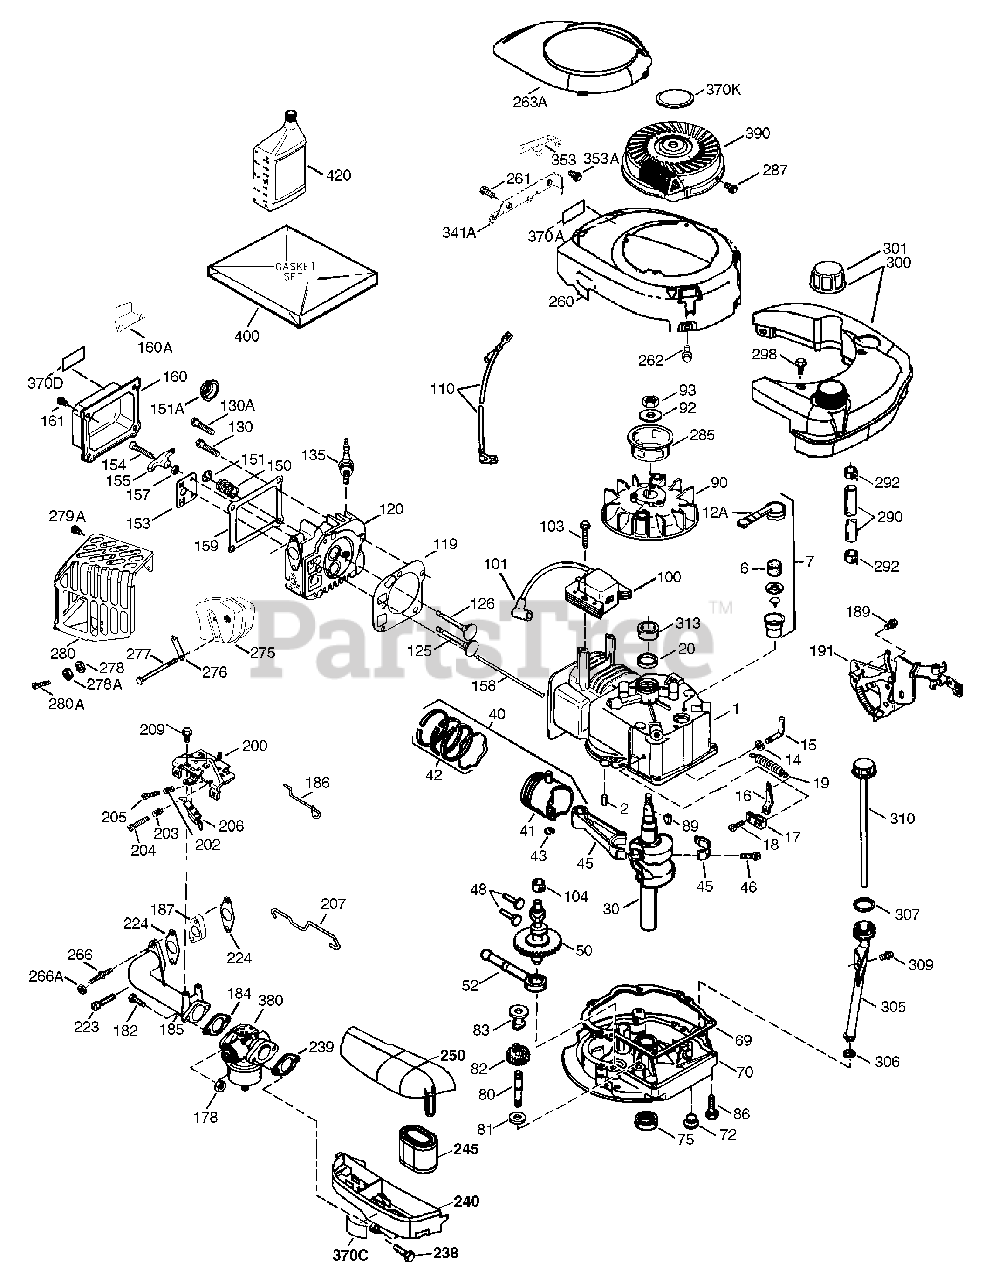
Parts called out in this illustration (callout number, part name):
1	Cylinder (Incl. 2 & 20)
2	Dowel Pin
6	Breather Element
7	Breather Body ASM(Incl. 6 & 12A)
12A	Breather Cover & Tube
14	Washer
15	Governor Rod(Incl. 14)
16	Governor Lever
17	Governor Lever Clamp
18	Screw, Torx T-15
19	Extension Spring
20	Oil Seal
30	Crankshaft
40	Piston, Pin & Ring Set(Std.)
40	Piston, Pin & Ring Set(.010" OS)
40	Piston, Pin & Ring Set(.020" OS)
41	Piston & Pin ASM(Std.)
41	Piston & Pin ASM(.010" OS)(Incl. 43)
41	Piston & Pin ASM(.020" OS)(Incl. 43)
42	Ring Set (Std.)
42	Ring Set (.010" OS)
42	Ring Set (.020" OS)
43	Piston Pin RetainingRing
45	Connecting Rod ASM(Incl. 46)
46	Connecting Rod Bolt
48	Valve Lifter
50	Camshaft Exhaust(MCR)(Incl. Ref #104)
52	Oil Pump ASM
69	Mounting FlangeGasket
70	Mounting Flange(Incl. 72 thru 83)
72	Oil Drain Plug
75	Oil Seal
80	Governor Shaft
81	Washer
82	Governor Gear ASM(Incl. 81)
83	Governor Spool
86	Screw
89	Flywheel Key
90	Flywheel
92	Belleville Washer
93	Flywheel Nut
100	Solid State Ignition
101	Spark Plug Cover
103	Screw, Torx T-15
104	Cam Bushing
110	Ground Wire
119	Cylinder Head Gasket
120	Cylinder Head
125	Exhaust Valve (Std.)(Incl. 151)
125	Exhaust Valve (1/32 OS)(Incl. 151)
126	Intake Valve (Std.)(Incl. 151)
130	Screw
130A	Screw
135	Resistor Spark Plug(RN4C)
150	Valve Spring
151	Valve Spring Cap
151A	Intake Valve Seal
153	Push Rod Guide
154	Rocker Arm Stud
155	Rocker Arm
157	Lock Nut
158	Push Rod
159	Rocker Arm Cover Gasket
160A	Heat Shield
161	Screw, Torx T-30
178	Nut & Lock Washer
182	Screw
184	Carburetor To IntakePipe Gasket
185	Intake Pipe
186	Governor Link
187	Spacer
189	Screw
191	S.E. Brake Bracket
200	Control Bracket (Incl. 202 Thru 206)
202	Compression Spring
203	Compression Spring
204	Screw, Torx T-10
205	Screw, Torx T-10
206	Terminal
207	Throttle Link
209	Screw
223	Screw
224	Intake Pipe Gasket
238	Screw
239	Air Cleaner Gasket
240	Air Cleaner Body
245	Air Cleaner Filter
250	Air Cleaner Cover
260	Blower Housing
261	Screw, Torx T-30
262	Screw
263A	Starter Grill
266	Screw
266A	Lockwasher
275	Muffler(Incl. 276 & 277)
276	Locking Plate
277	Screw
278	Spacer
278A	Bushing Control Lever
279A	Screw, Torx
280	Heat Shield-Muffler
280A	Screw
285	Starter Cup
287	Screw
290	Fuel Line
292	Fuel Line Clamp
298	Screw
300	Fuel Tank (Incl. 292 & 301)
301	Fuel Cap
305	Oil Fill Tube
306	"O"-Ring
307	"O"-Ring
309	Screw
310	Dipstick
313	Spacer
341A	Offset Bracket
353	Bracket Spacer
353A	Screw
370A	Lubrication Decal
370C	Primer Decal (3X)
370D	Caution Decal
370K	Starter Decal
380	Carburetor (Incl. 184)
390	Rewind Starter
400	Gasket Set
420	SAE30 4-Cycle Engine Oil (Quart)
